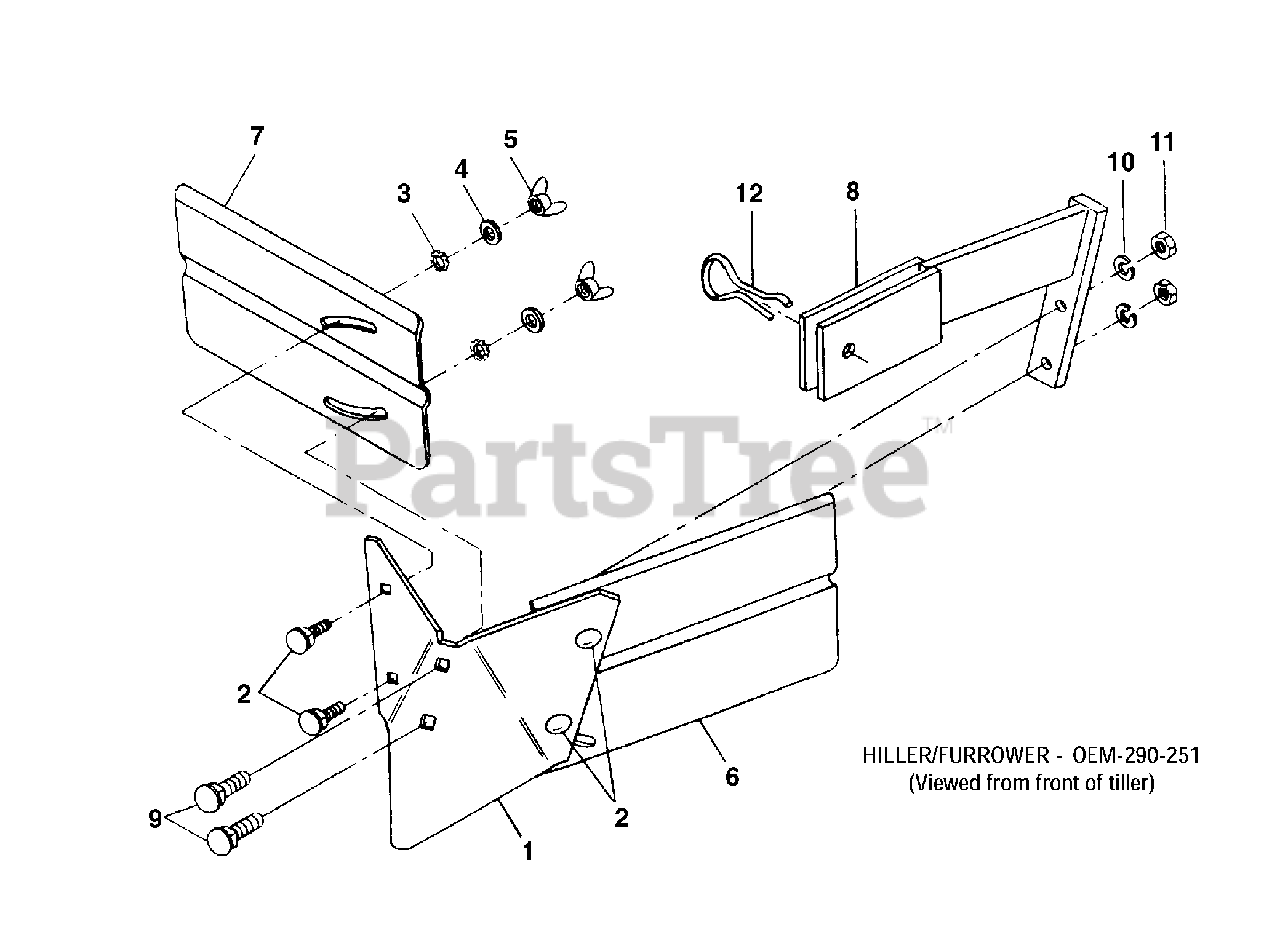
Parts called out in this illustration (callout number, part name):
1	Furrower Blade
2	Carriage Bolt, 5/16-18 x 3/4
3	Star Washer, External Tooth, 5/16
4	Plain Washer, 5/16 S.A.E.
5	Wing Nut, 5/16-18.
6	Hiller Wing, left
7	Hiller Wing, right
8	Blade Mounting Bracket
9	Carriage Bolt, 3/8-16 x 1-1/2
10	Lockwasher, 3/8, plated
11	Hex Nut, 3/8-16, plated
12	Clinch Pin
